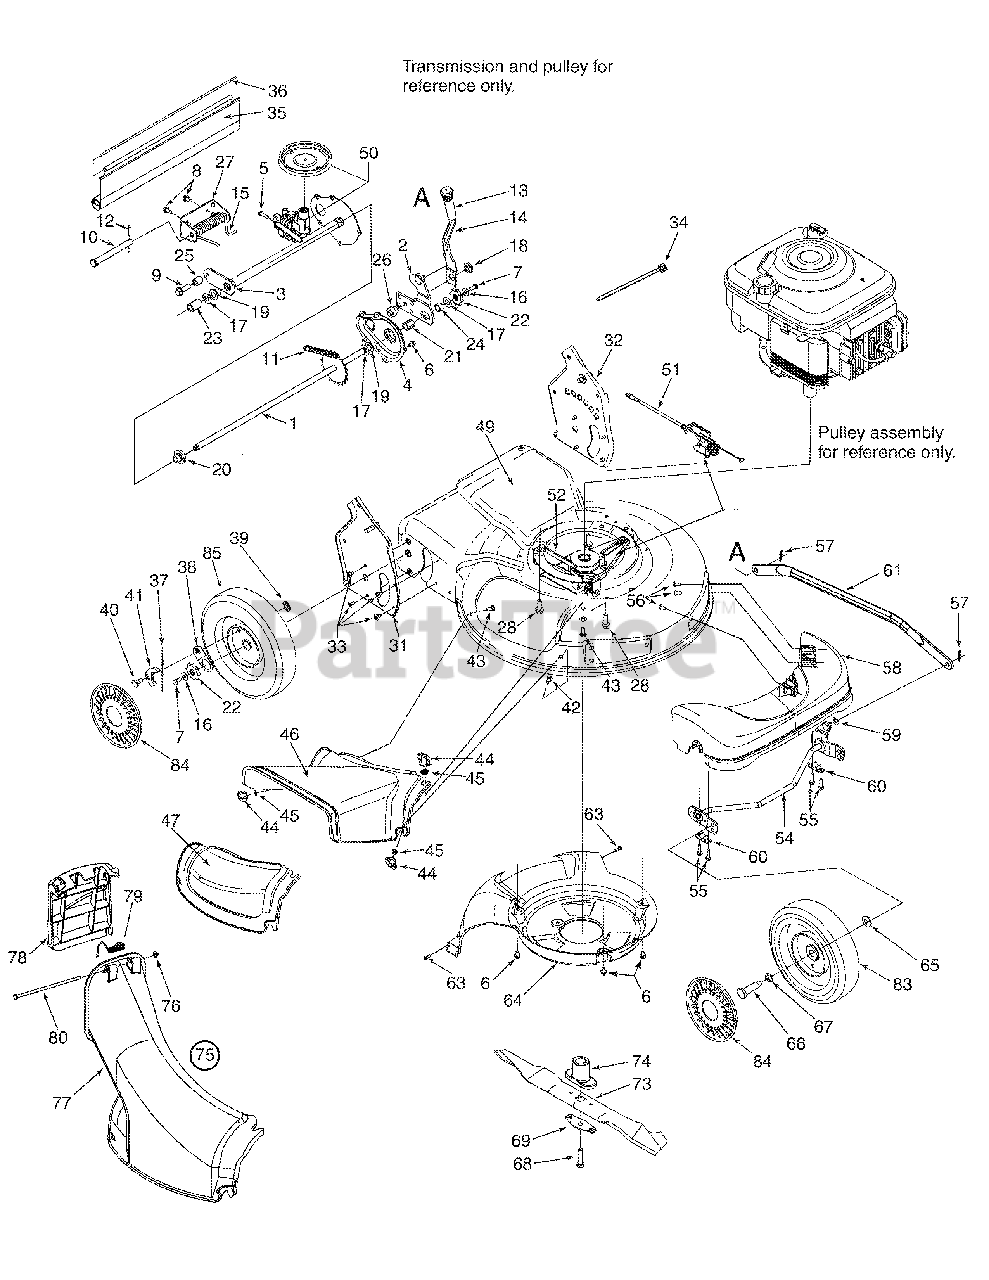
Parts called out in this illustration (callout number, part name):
1	Axle Ass’y 20T x 21.46" Lg.
2	Pivot Arm Ass’y
3	Trans Axle Ass’y
5	Hex Wash HD Scr 5/16-18 x .62
6	Hex Wash HD Tapp Scr 1/4-20 x .38
7	Hex Bolt 1/4-20 x .62
8	Hex Wash HD. TT Tap Scr. 1/4-20 x .62
9	TT Screw 3/8-16 x 1.25
10	Clevis Pin .5" Dia. x 4.62" Lg.
11	Chain, No. 48 End less .50 x 24 links
12	Cotter Pin
15	RH Torsion Sprocket
16	Cupped Wash. .25 ID x .88 OD x .062
17	Washer, Flat .505 ID x 1.0
18	Shoulder Nut .625 DIA. x .165
19	Flange Bearing .506 ID
20	Hex Flange Bearing
21	Hex Sleeve Bearing .504 x .830 Lg.
22	Ratchet Wheel
23	Spacer .55 ID x .75
24	Sleeve .511 id x .70 od x .37" lg.
25	Spacer .38 x .625" Lg.
26	Shoulder Spacer .385 ID x .715" Lg.
27	Spring Bracket
28	Hex Wash HD Tap Scr 3/8-16 x .88
29	Hex Wash Hd Screw 10-32 x 5/8
30	Clamp Casing - Throttle
31	Handle Brkt. Ass’y RH
32	Handle Brkt. Ass’y LH
33	Screw AB 1/4-20
35	Rear Flap 17.25" Lg.
37	Spring Nylon
38	Pawl Plate
39	Toplock Flat Weldnut 1/4-20
40	Shoulder Screw .340 x .285: 1/4-20
42	Carriage Bolt 1/4-20 x .62
43	Carriage Bolt 1/4-10 x .75
44	Wing Nut
45	Bolt Retainer 1/4" x .50" OD
47	Mulching Baffle
49	Deck Ass’y (w/o logo)
50	Transmission Ass’y
51	SP Cable 51.0" Lg.
52	V-Belt 3/8 x 39.24" Lg.
55	Hex Wash. Hd. B-Tap Scr. 1/4 x 1.0" lg
56	Torx Hd. Scr. 5/16 x .75
57	Int. Cotter Pin 5/16 DIA
58	Front Cover- Grey
59	Bowed Washer
60	Bushing Block .505 dia.
61	Single Lever Arm Control
63	Screw 1/4-15 X .75
64	Baffle
65	Cupped Wash .400 ID x .88 OD x .06
66	Axle Bolt
67	Wave Washer .51" ID
68	Hex Bolt 3/8-24 x 2.5" Lg.
69	Bell Blade Support
73	Blade 21" (mulching)
74	Blade Adapter (w/star)
75	Chute Assembly
76	Push Cap .188 Rod
79	Torsion Spring
83	Front Wheel Ass'y 8 x 2.125 (Idle/Zag Ball Brg)
84	Hub Cap -Grey
85	Rear Wheel Ass’y 9 x 2.125 (Drive/Zag/Blk)
